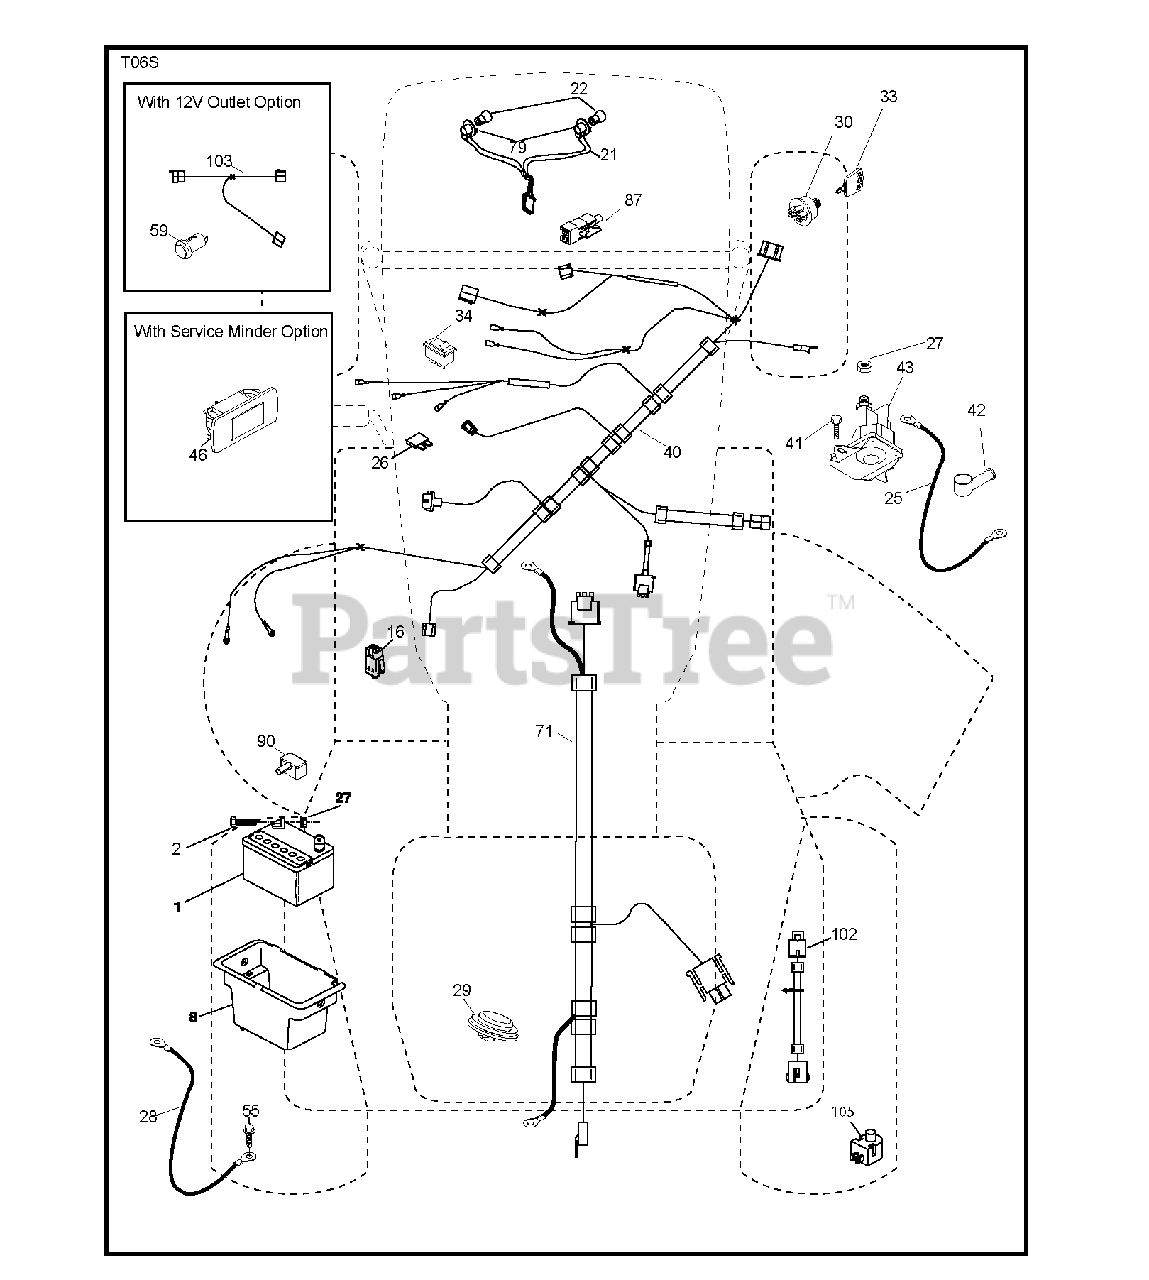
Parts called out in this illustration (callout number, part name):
1	REPL BY 532 12 38-99
8	BOX.BATTERY.MNT.REAR.L
16	SWITCH INTERLOOK PUSH-IN
21	HARNESS.LIGHT W/4152J BULBS
22	LIGHTBULB
25	CABLE.STARTER.6GA.BL/RED.14.
26	FUSE 20AMP
27	NUT
28	CABLE.BLACK.18"REAR.BA
29	SWITCH.SEAT.DELTA.OPC.
30	SWITCH.IGN.DELTA.W.LGH.ROS
33	KEY.CHAIN.BLISTER.PACK.GEN.USA
34	SWITCH LT
40	HARNESS IGN. DASH
41	SCREW
42	TERMINAL COVER
43	SOLENOID.W/BRASS.PLUNG
55	SCREW 5/16"
71	HARNESS.IGN.CHASS.TEX.REAR.BAT
79	BULB HOLDER ASM.
87	SWITCH.INTRLCK.CLUTCH.
90	COVER, TERMINAL BATTERY
102	HARNESS PIGTAIL PCH TEX ROS
105	REVERSE SWITCH
